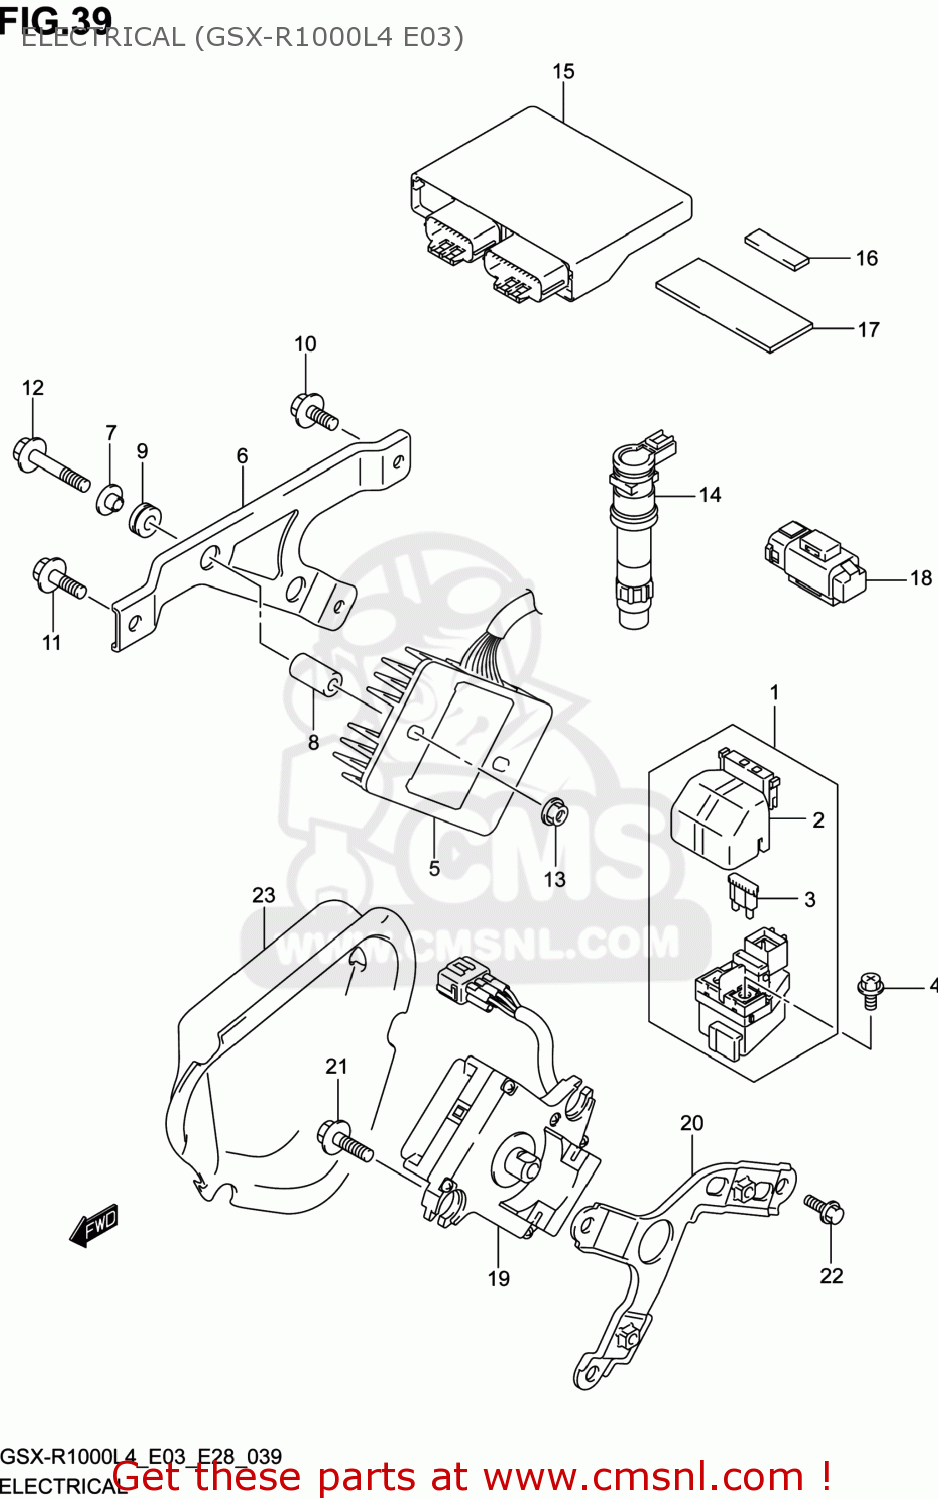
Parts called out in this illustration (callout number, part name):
1	RELAY ASSY,STARTING MOTOR
2	COVER
3	FUSE(30A)
4	SCREW(6X8)
5	RECTIFIER ASSY
6	BRACKET,RECT FTG
7	SPACER(6.2X8.4X6.9)
8	SPACER(6.2X14.5X26)
9	CUSHION
10	BOLT
11	BOLT(6X20)
12	BOLT
13	NUT
14	COIL ASSY,IGNITION
15	CONTROL UNIT,FI
16	CUSHION,FI CONTROL UNIT
17	PROTECTOR(30X80X2)
18	SENSOR ASSY,FUEL CUT
19	ACTUATOR ASSY,EXHAUST CONTROL
20	HOLDER,ACTUATOR
21	BOLT(6X25)
22	BOLT
23	COVER,ACTUATOR
